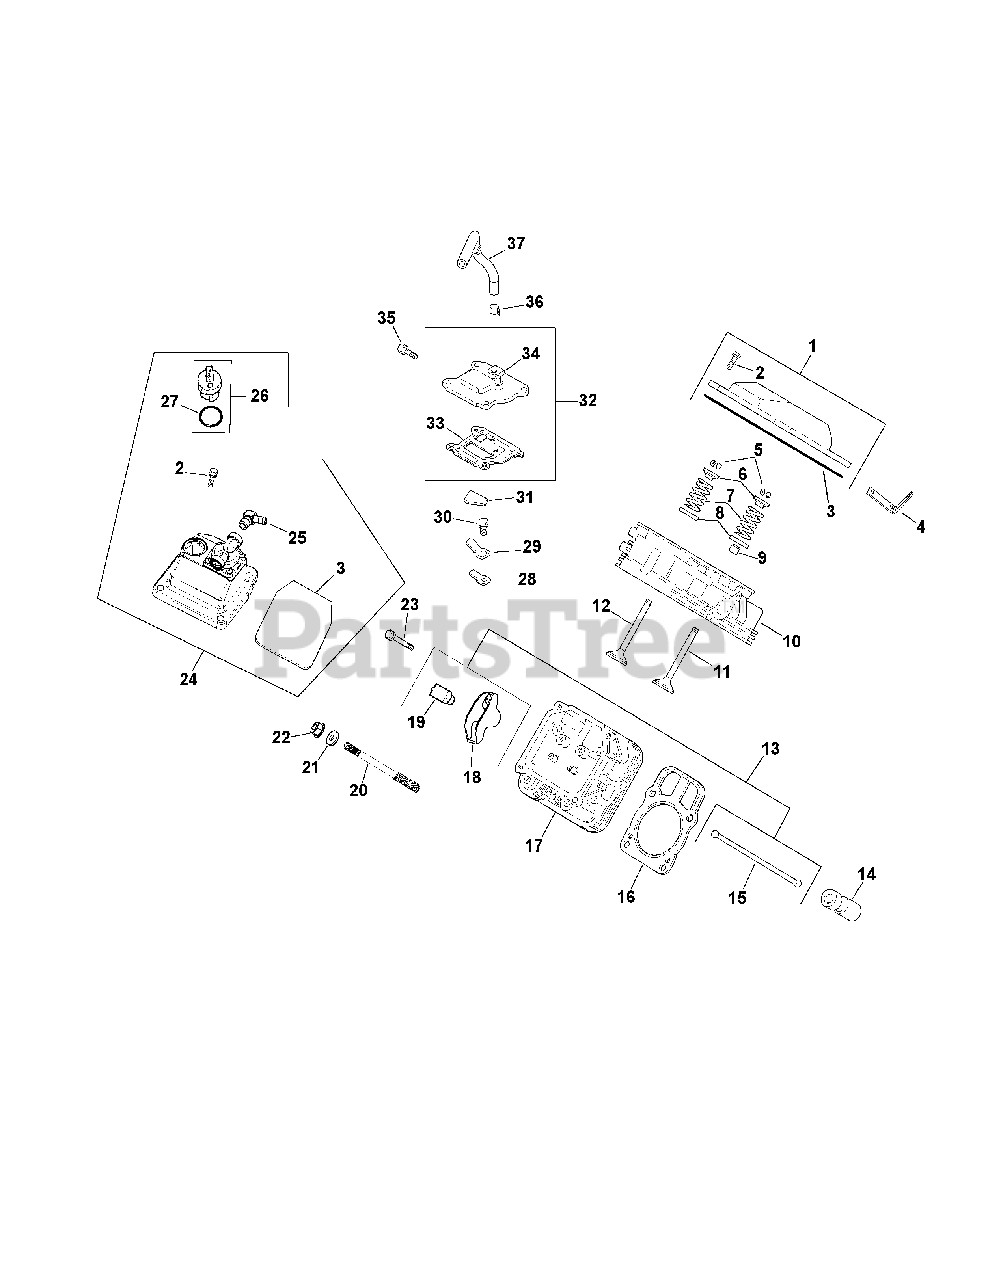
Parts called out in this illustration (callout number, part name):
1	Kit, valve cover - plain (Includes 2,3)
2	Screw, hex flange M6x1.0x30 (4)
3	O-Ring, valve cover
4	Strap, lifting
5	Kit, retainer (4)
6	Cap, valve spring (4)
7	Spring, valve (4)
8	Retainer, spring (4)
9	Seal, valve stem (2)
10	Head assembly, #1 cylinder
11	Valve, intake (Std ) (2)
12	Valve, exhaust (Std ) (2)
13	Kit, valve train (Includes 15,18,19)
14	Lifter, valve (4)
15	Rod, push (4)
16	Kit, cylinder head gasket (Includes 21,22) (2)
17	Head assembly, #2 cylinder
18	Arm, rocker (4)
19	Pivot, rocker arm (4)
20	Stud, cylinder head (8)
21	Washer, plain (8)
23	Screw, hex flange M6x1.0x34 (4)
24	Kit, fuel pump valve (Includes 2,3,25-27)
25	Fitting, 90° (2)
26	Cap assembly, oil fill (Includes 27)
27	O-Ring
28	Reed, breather
29	Retainer, breather reed
30	Screw, hex flange M5x0.8x10
31	Filter, breather
32	Kit, breather (Includes 33,34)
33	Gasket, breather
34	Cover, breather
35	Screw, hex flange M6x1.0x20 (4)
36	Clamp, breather
37	Hose, breather
